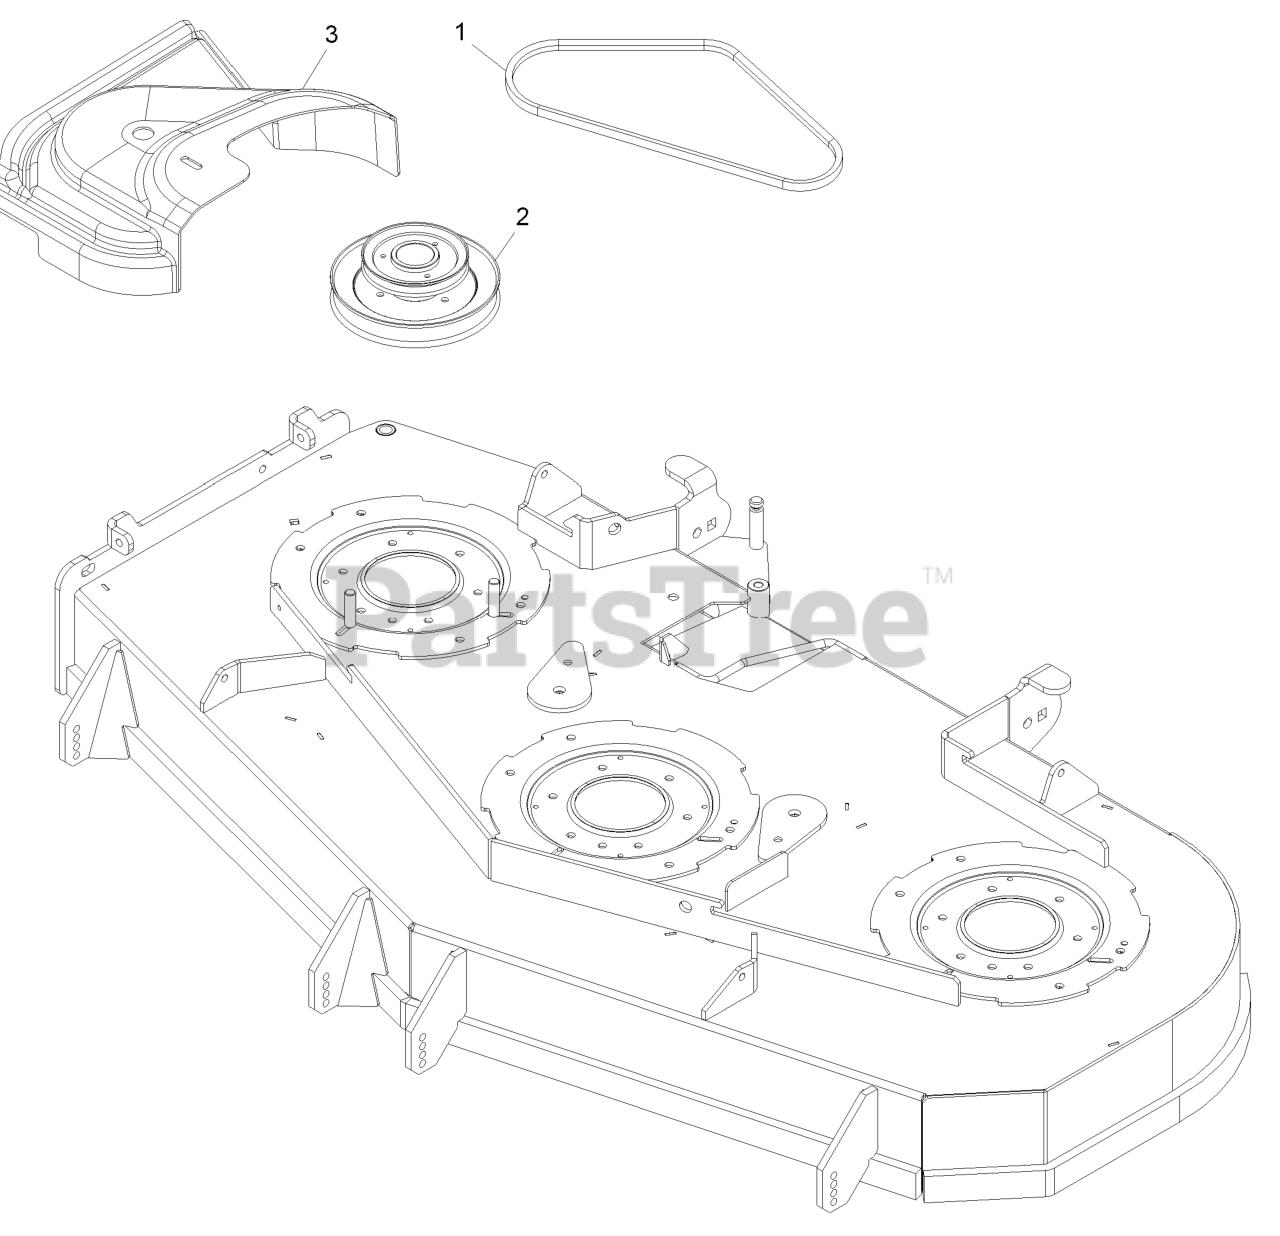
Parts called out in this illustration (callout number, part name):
1	BELT, BLOWER DRIVE 60
2	JACKSHAFT,UV DRIVE 604
3	COVER,BELT UV 60
